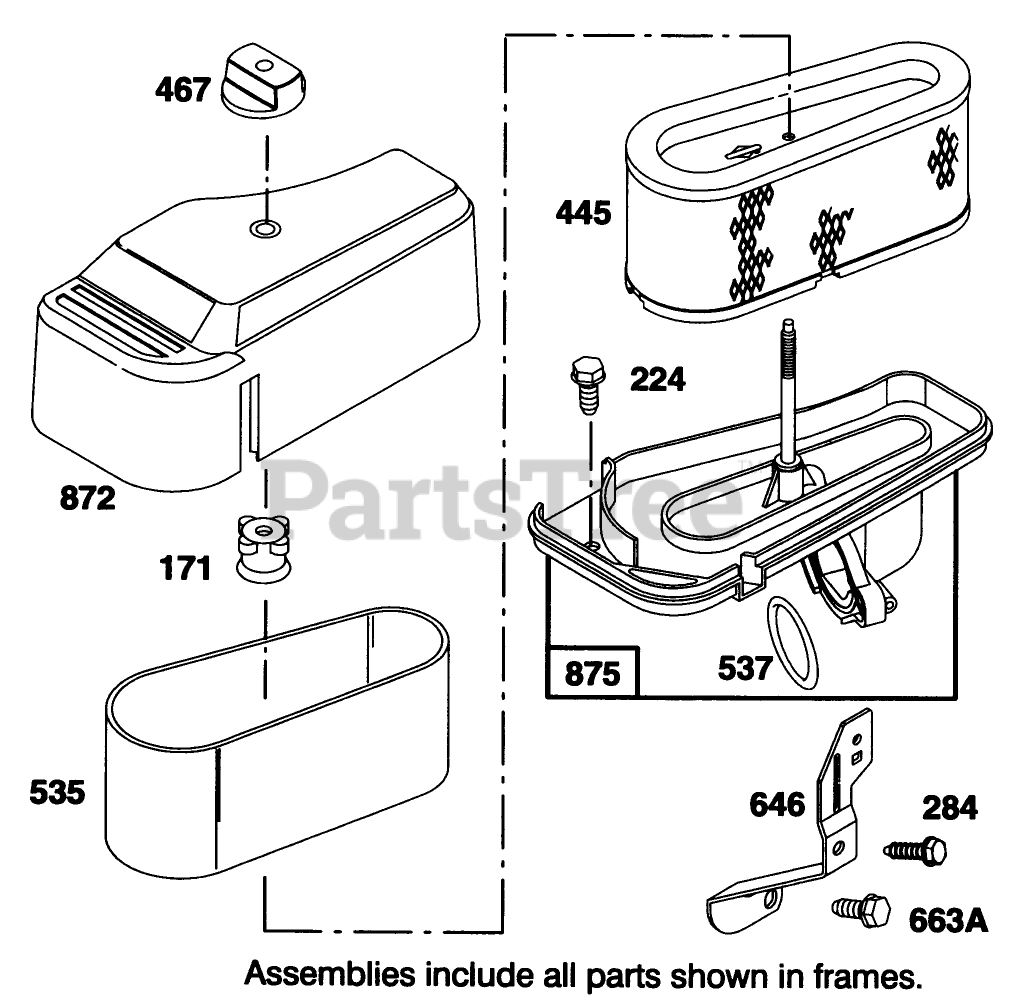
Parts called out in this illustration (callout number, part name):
224	Screw-Sem
284	Screw
445	Filter-Air
535	Filter-Air
537	O-Ring
646	Brace-Air Cleaner
663A	Screw
872	Cover-Air Cleaner
875	Body-Air Cleaner
